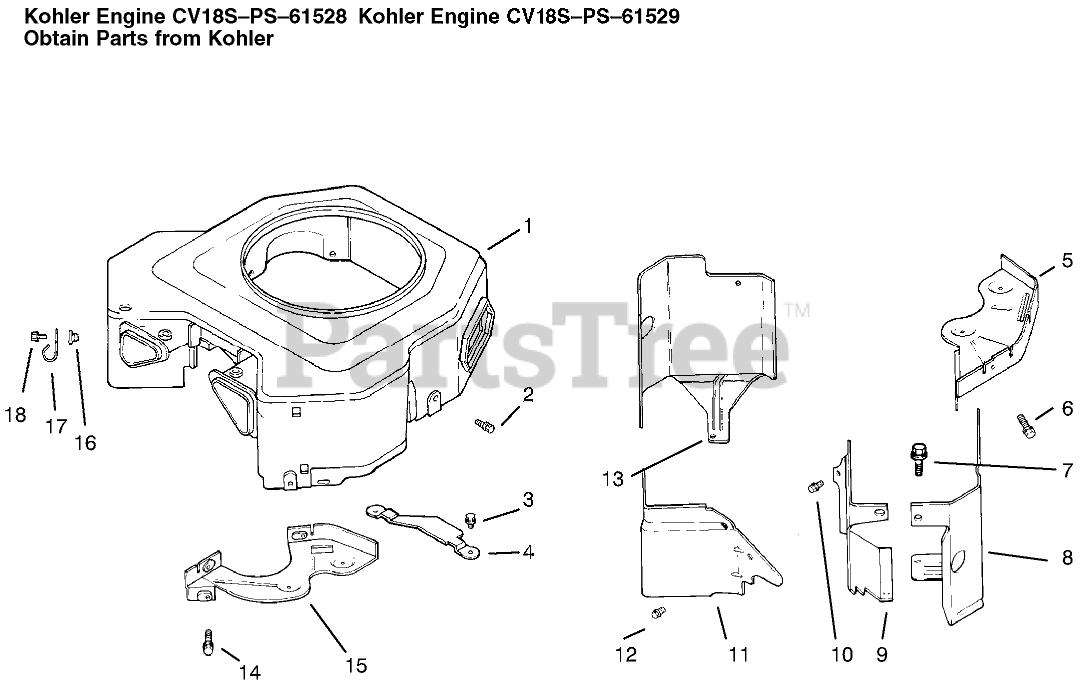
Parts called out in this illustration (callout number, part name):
1	Blower Housing ASM
3	Screw
4	Guard-Flywheel
5	Plate-Backing #2 Side
7	Screw
8	Baffle-Cylinder, #2
9	Baffle-Valley #1 Side
10	Screw
11	Baffle-Valley #2 Side
13	Baffle-Cyl. #1 Side
14	Screw
15	Plate-Backing #1
16	Nut
17	Clamp
18	Screw
